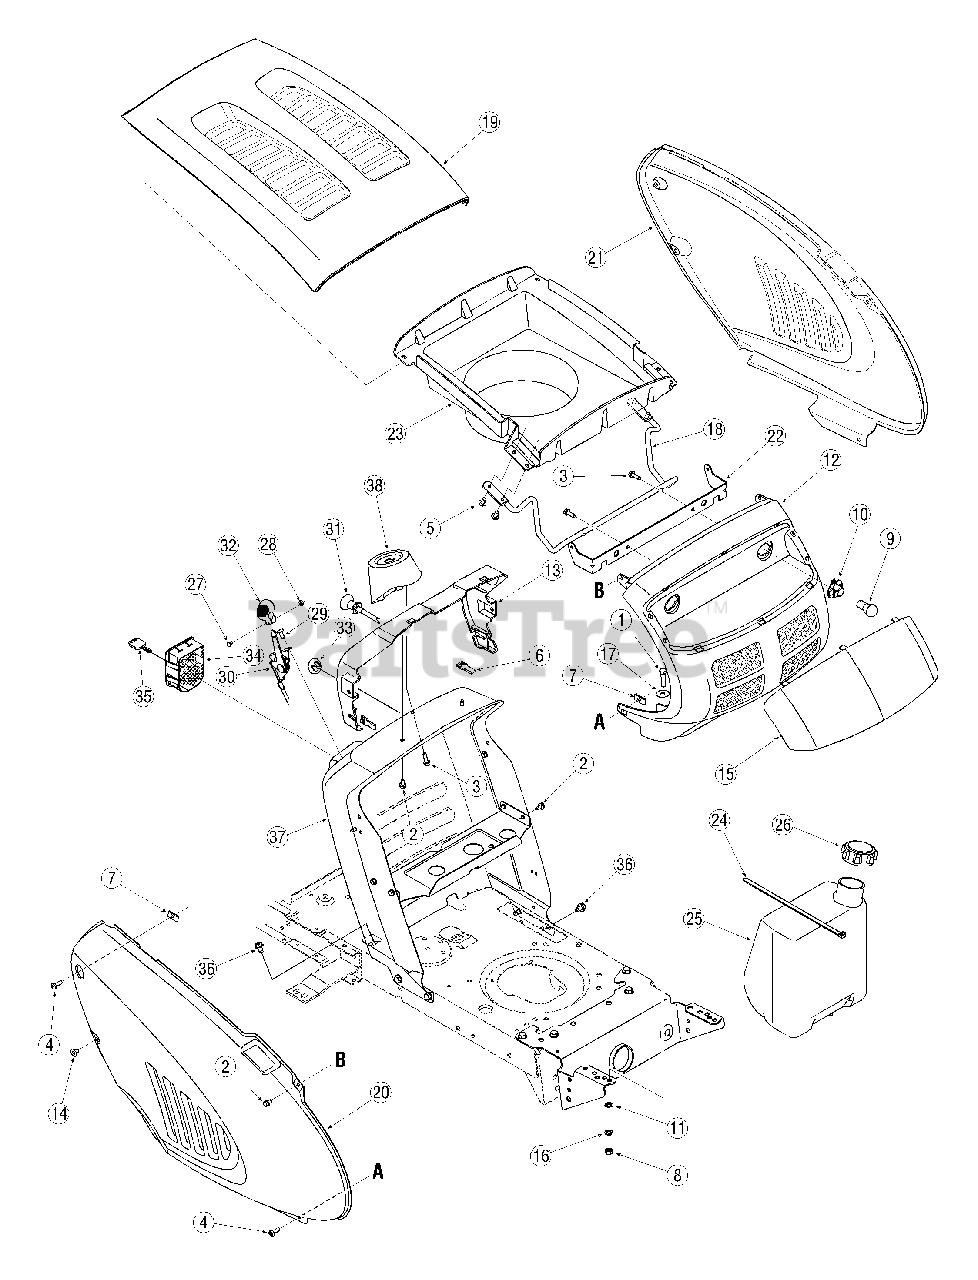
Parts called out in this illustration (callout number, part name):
1	Screw, 5/16-18, 1.25, Gr5
2	Screw, 1/4-20, 0.500
3	Screw, 1/4-15, 0.750
4	Screw, Machine, 1/4-20, 0.750
5	Screw, 1/4-14, 0.625
6	Speed Nut, U-type, 1/4-20
7	Nut, Tinn Clip, 1/4-20
8	Nut, Flange Lock, 5/16-18, Gr F, Nylon
9	Miniature Lamp 12V
10	Lamp Socket, Nylon 1/4-Turn
11	Nut, Speed, .3125 ID
12	Grill, 9 Style,
12	Grill, 9 Style, Service Kit
13	Collar, Dash
14	Plug, 0.285 Dia.
15	Lens
16	Washer, Lock, 5/16
17	Washer, Flat, .344 x 1.0 x .063
18	Rod, Hinge
23	Plenum (Single Cylinder Engine)
23	Plenum (Twin Cylinder Engine)
24	Cable Tie, 34.75
25	Fuel Tank, 1.5 gal.
26	Fuel Tank Cap
27	Screw, Machine, #8-32, 0.375
28	Nut, Hex, #8-32, Gr A
29	Screw, 1/4-14, .625
30	Throttle/Choke Control, 25" (Single Cylinder Engine)
30	Throttle Control, 39" (Twin Cylinder Engine)
31	Choke Control, 37.5"
32	Knob, Control
34	Module, Ignition Switch
35	Key
36	Screw, 5/16-18, 0.500
38	Support, Steering
